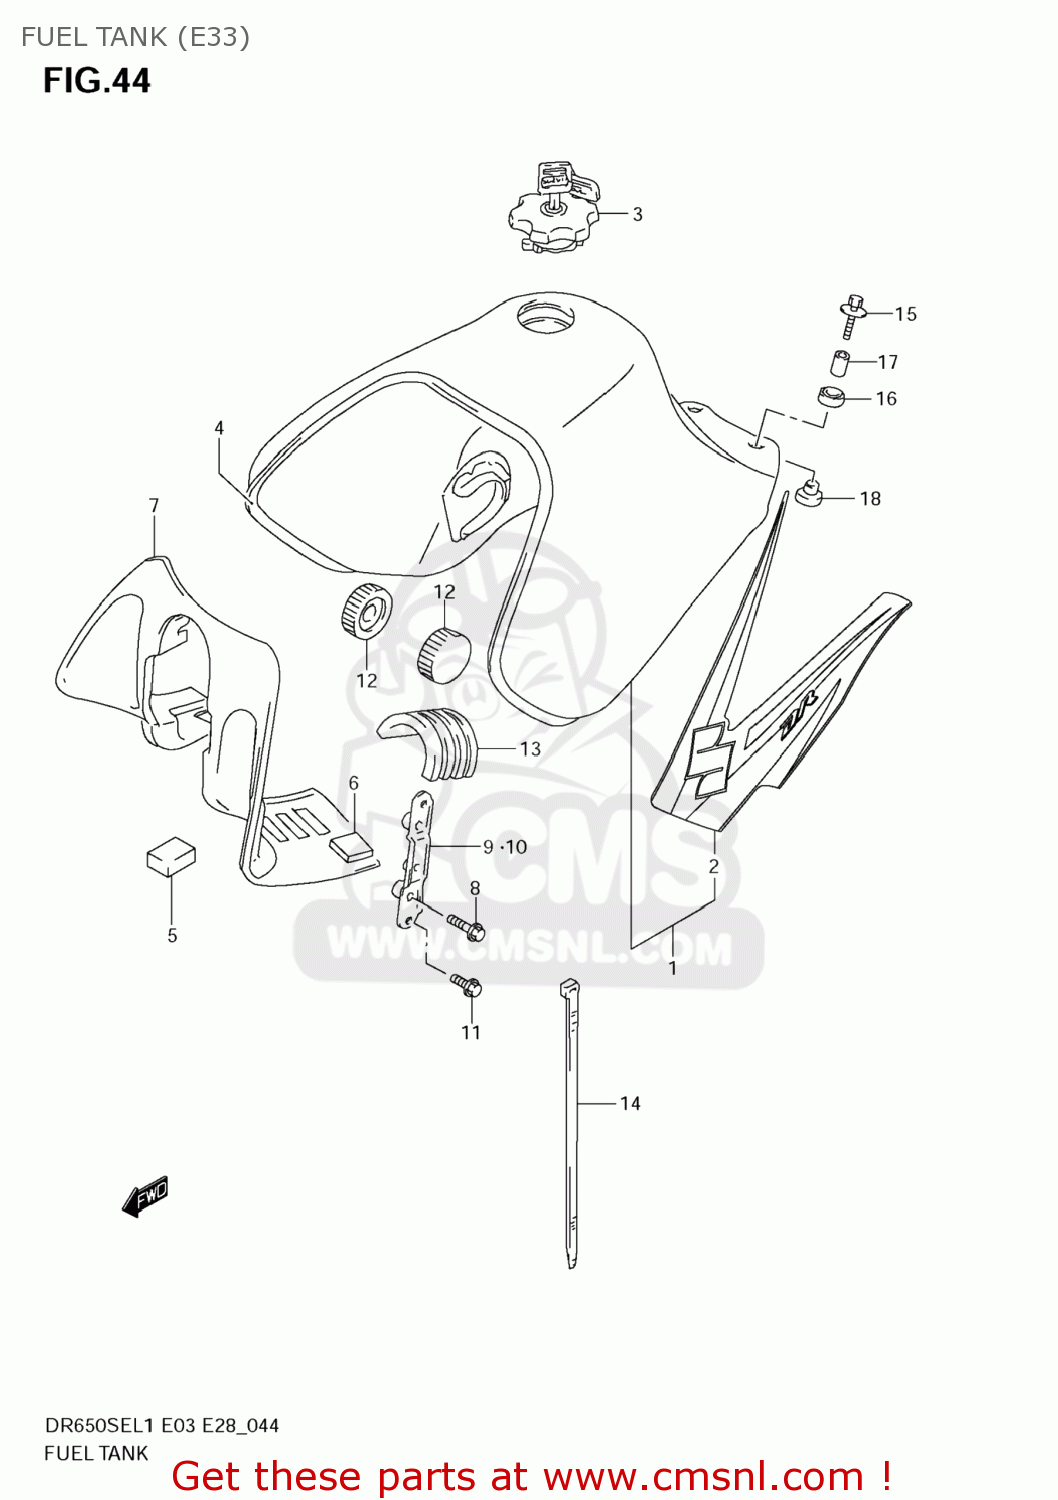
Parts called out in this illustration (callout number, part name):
1	TANK ASSY,FUEL(BLACK)
2	TAPE SET,FUEL TANK
3	CAP SET,FUEL TANK
4	MOLDING,FUEL TANK
5	CUSHION,HEAD LAMP HOUSING
6	CUSHION,OIL TANK UPR
7	COVER,FUEL TANK FR
8	BOLT(6X12)
9	BRACKET,FUEL TANK COVER,R
10	BRACKET,FUEL TANK COVER,L
11	BOLT
12	CUSHION,FUEL TANK FR
13	CUSHION,FUEL TANK UPR
14	CLAMP(L:250)
15	BOLT(6X30)
16	CUSHION
17	SPACER(6.5X9X18)
18	CUSHION
